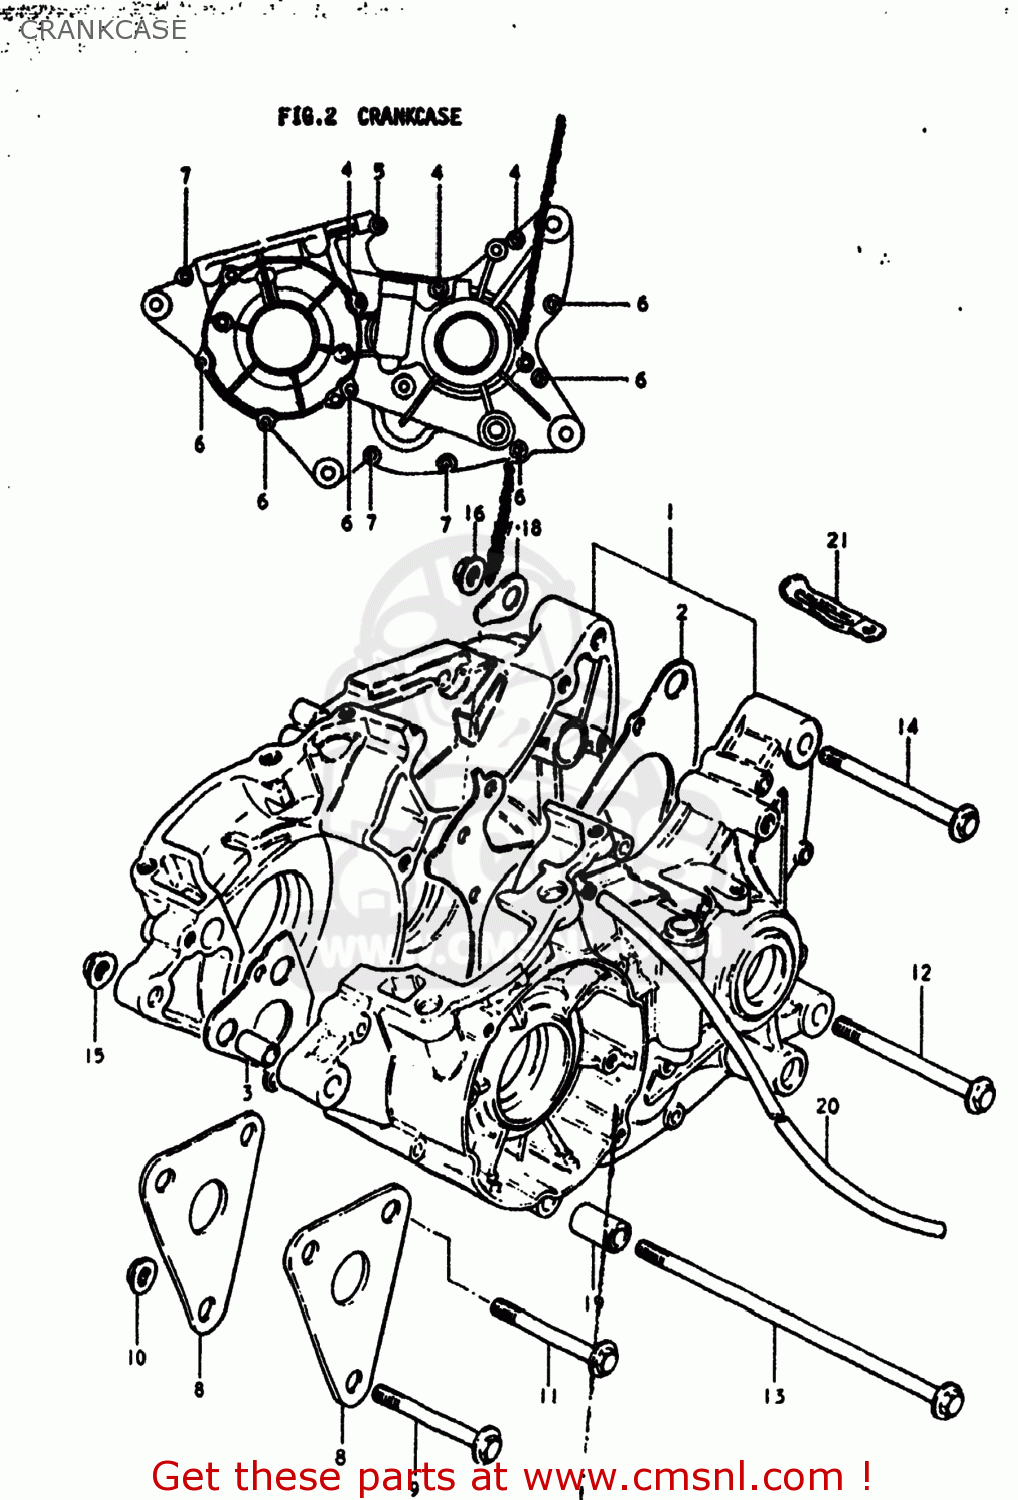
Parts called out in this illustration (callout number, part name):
1	CRANKCASE SET
2	GASKET,CRANKCASE (MCA)
3	PIN
4	SCREW 6X65
5	SCREW
6	SCREW
7	SCREW (6X35)
8	PLATE,ENGINE MOUNTING
9	BOLT(8X67)
10	NUT
11	BOLT(8X67)
12	BOLT
13	BOLT
14	BOLT
15	NUT
16	NUT
17	WASHER
18	WASHER
19	SPACER(8.6X16X26)
20	HOSE
21	CLAMP
